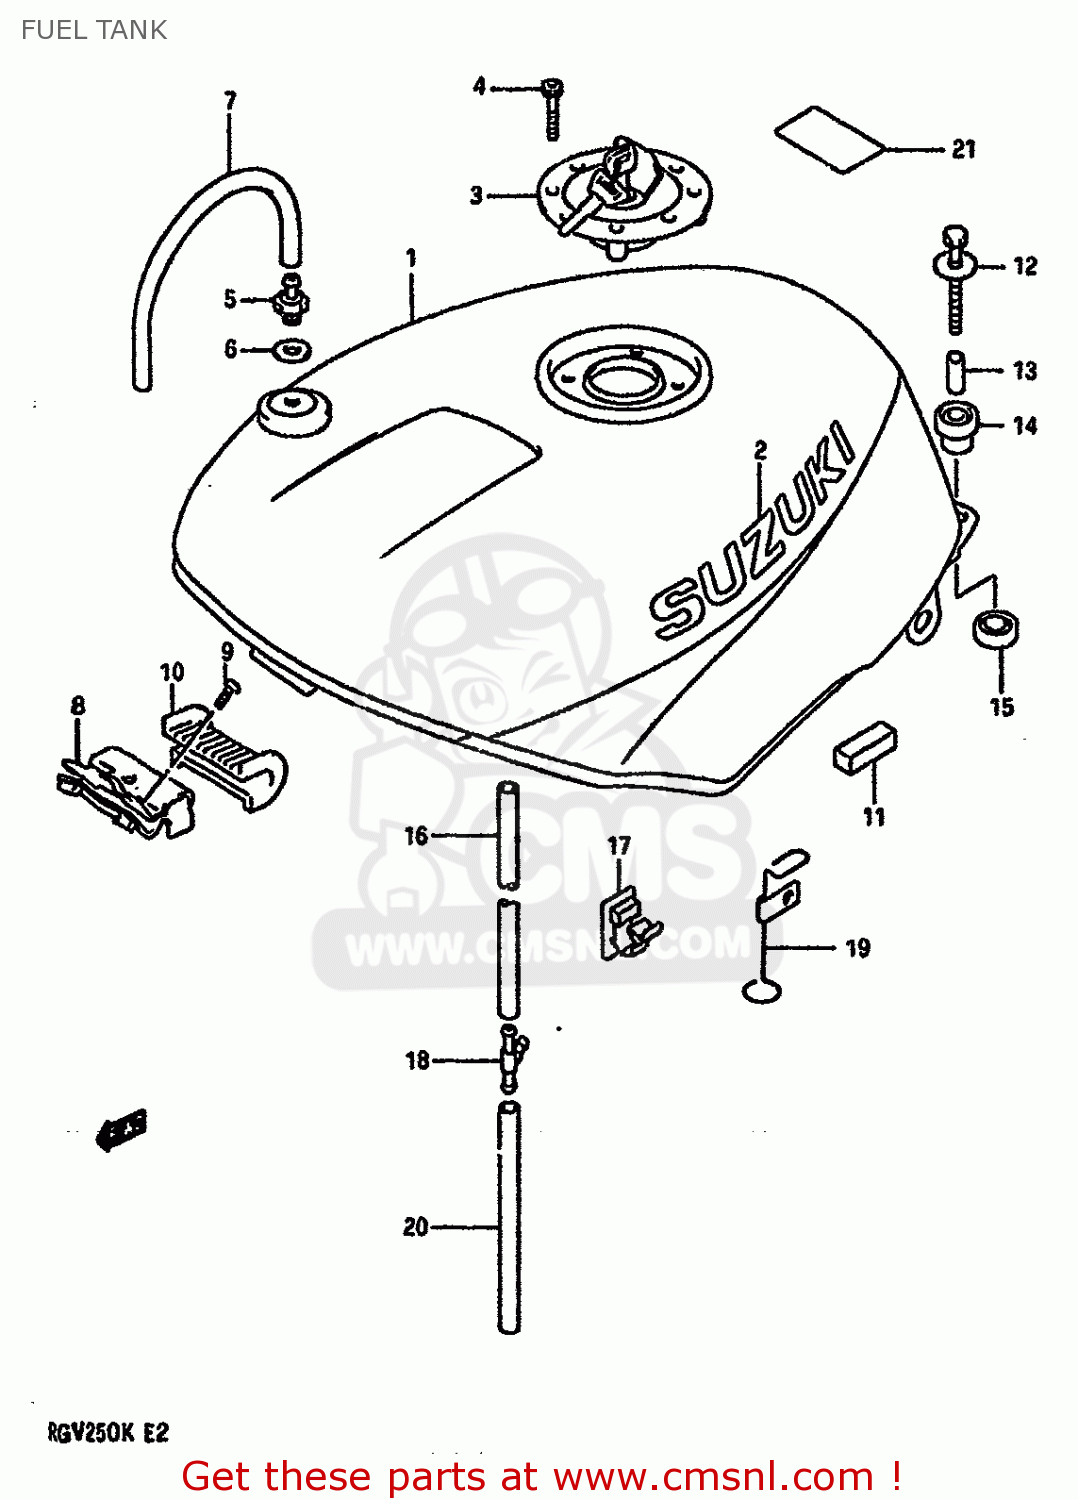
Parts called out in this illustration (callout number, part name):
1	TANK ASSY,FUEL (WHITE/BLUE)
2	EMBLEM,FUEL TANK (BLUE)
3	CAP SET,FUEL TANK
4	BOLT(5X20)
5	PLUG,FUEL TANK BREATHER
6	GASKET(12.5X20X2.5) (NAS)
7	HOSE
8	BRACKET,FUEL TANK
9	SCREW
10	CUSHION,FUEL TANK,FRONT
11	CUSHION,FUEL TANK SIDE
12	BOLT(6X35)
13	SPACER
14	CUSHION
15	CUSHION
16	HOSE
17	CLAMP
18	3 WAY
19	GUIDE,DRAIN HOSE
20	HOSE
21	LABEL,FUEL CAUTION
